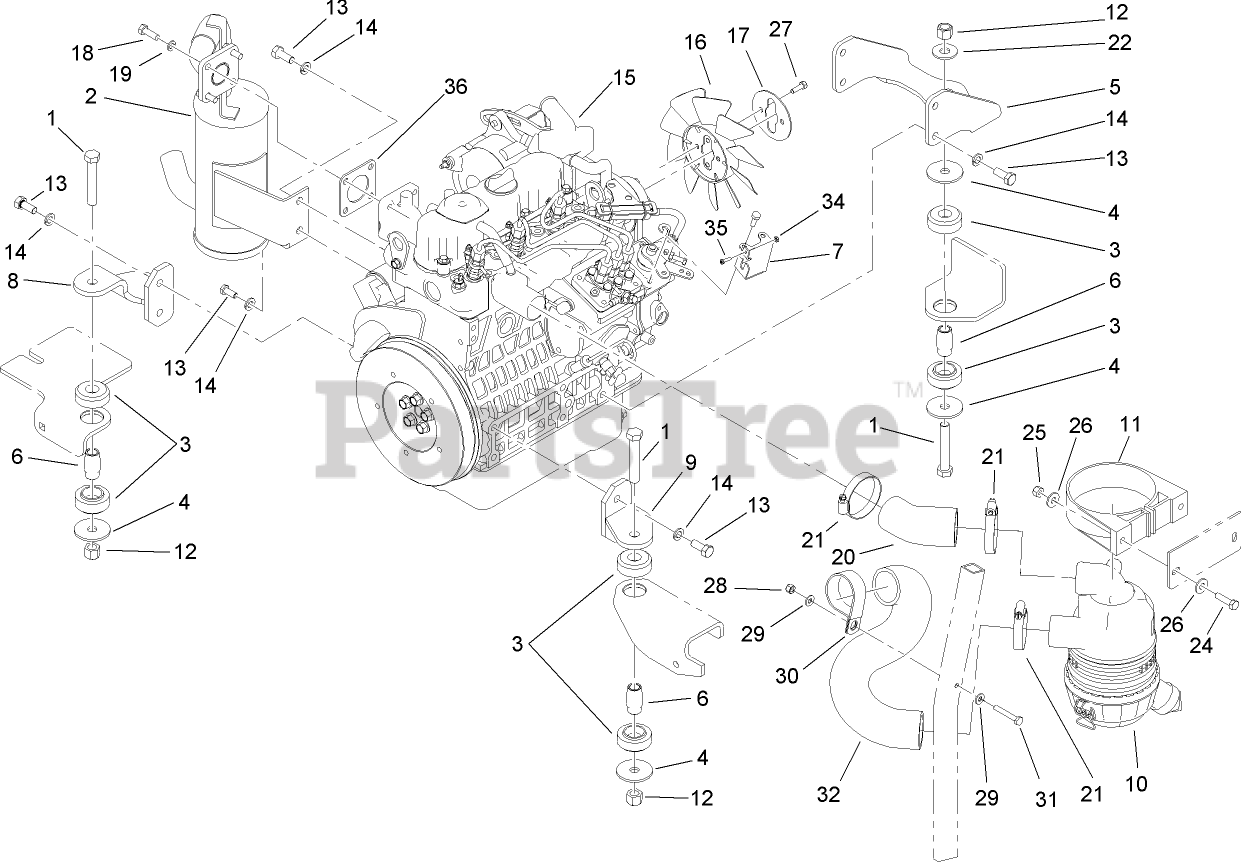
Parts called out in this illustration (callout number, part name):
1	SCREW-HH
2	MUFFLER
3	MOUNT-ISOLATION ASM
4	WASHER-LARGE
5	BRACKET-ENGINE MOUNT, REAR
6	SPACER
7	BRACKET-SUPPORT, THROTTLE
8	SUPPORT-ENGINE, RH
9	SUPPORT-ENGINE, LH
10	AIR CLEANER ASM
11	BRACKET-MOUNTING
12	NUT-LOCK, NI
13	SCREW-HH
14	WASHER-LOCK, SPRING
15	ENGINE-KUBOTA
17	PLATE-REATAINER, FAN
18	SCREW-HH
19	WASHER-LOCK
20	HOSE-OUTLET, AIR CLEANER
21	CLAMP-HOSE
22	WASHER-FLAT
24	SCREW-HH
25	NUT-LOCK, NI
26	WASHER-PLAIN
27	SCREW-HH
28	NUT-LOCK, NI
29	WASHER-FLAT
30	CLIP-LOOM
31	SCREW-HH
32	HOSE-INLET, AIR CLEANER
34	NUT-HEX
35	SCREW-TORX
36	GASKET-MUFFLER
